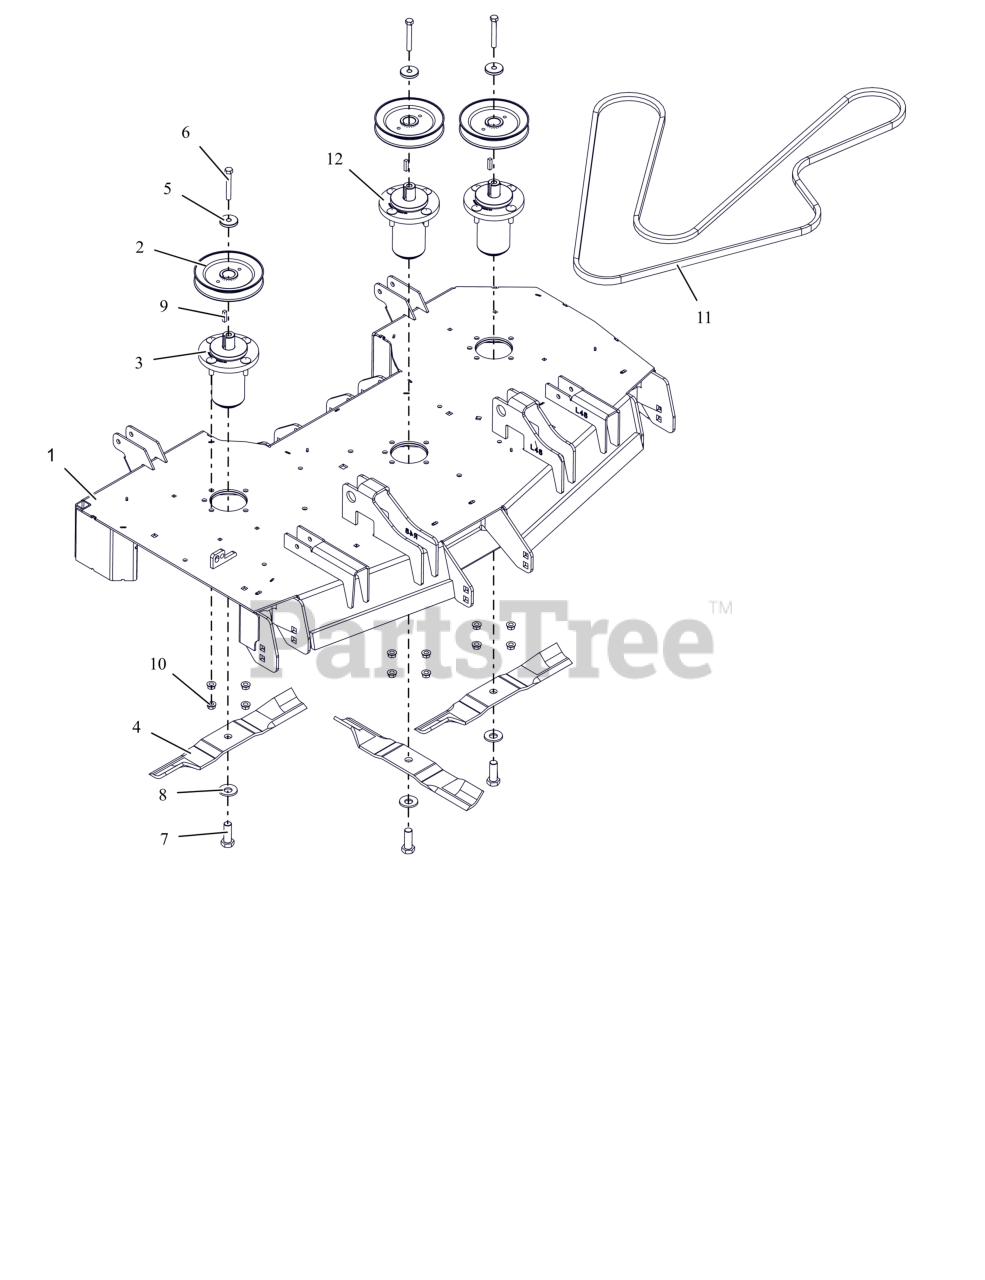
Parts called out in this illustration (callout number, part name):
1	KIT- SERVICE 48" DECK W/DECALS
2	PULLEY, V - 1.000 ID X 5.750 OD
3	ASM, ALUM SPINDLE
4	BLADE, MOWER - 16.19"
5	RETAINER, SHEAVE
6	BLT, HEX .38-16X2.75 G8 ZCC
7	BLT, HEX .62-18X1.75 G8 ZCC
8	WSHR-BLVL .669X1.535X.138
9	KEY, SQ .25X.25X1.00 RC 40-50
10	NUT-LK-CTR-FLG .375-16 GF ZCC
11	BELT, B-SECTI0N EPDM RAW EDGE
12	ASM, MAINT FREE ALUM SPINDLE
